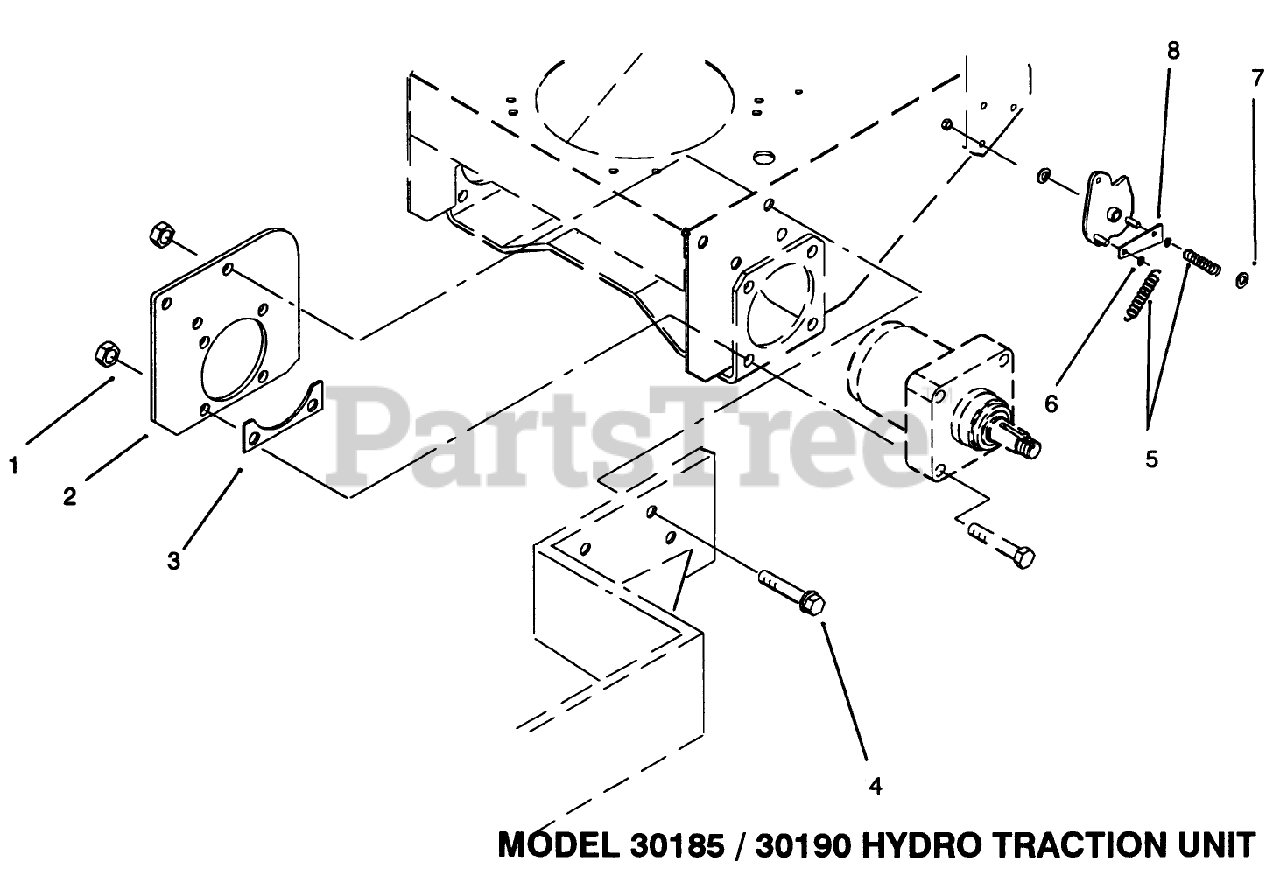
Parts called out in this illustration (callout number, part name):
1	Nut
2	Plate-Frame
3	Spacer
4	SCREW-HHF
5	SPRING-EXTENSION
6	NUT-PUSH IN
7	NUT-PUSH
8	STOP BRACKET
